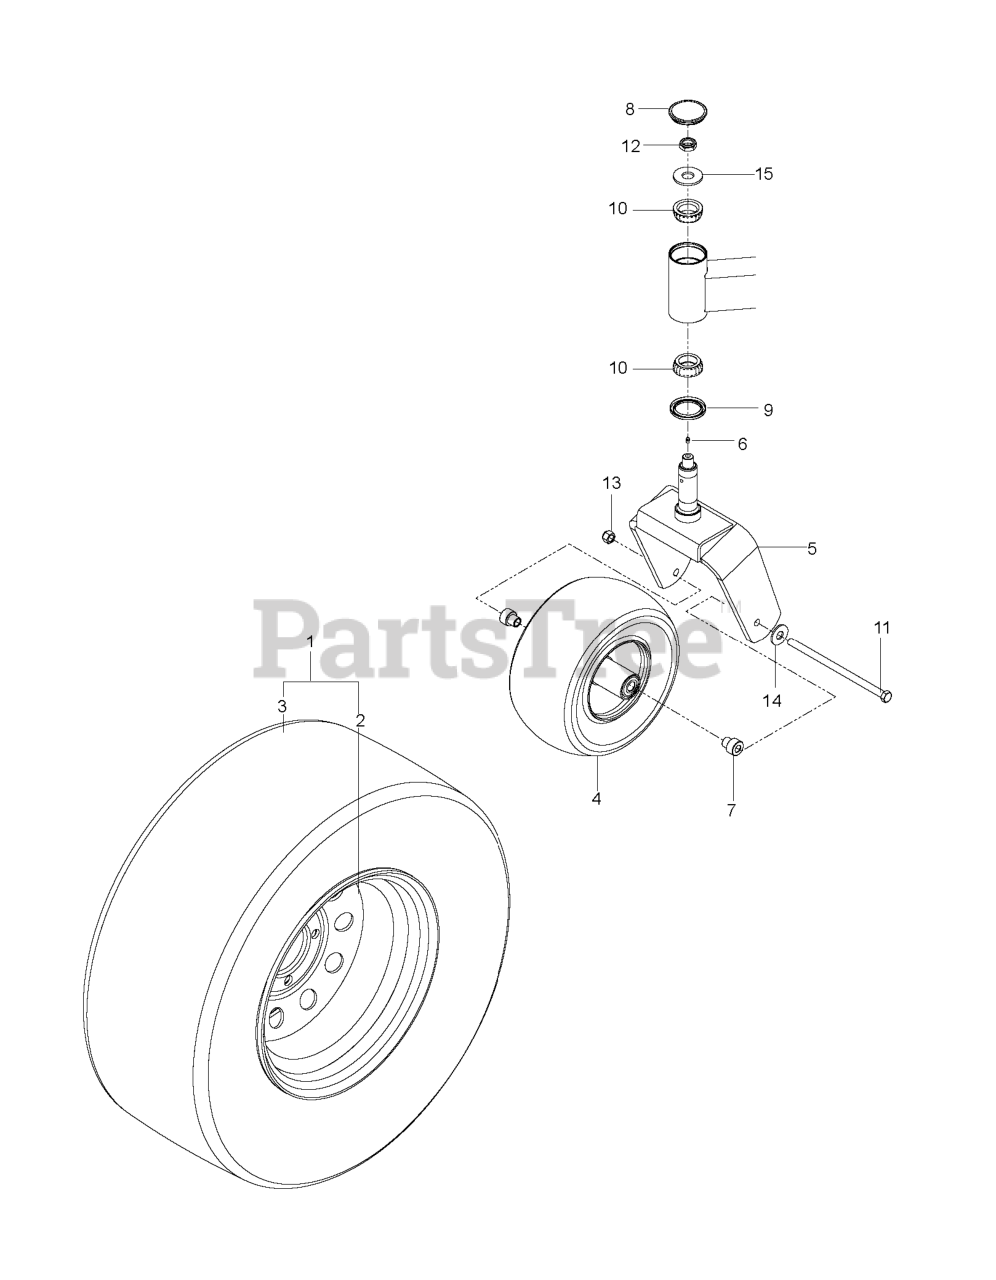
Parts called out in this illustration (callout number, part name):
1	WHEEL/TIRE.ASM.24X12-12.SILVER
2	12"RIM 2.5" NEG OFFSET 8.5" W
3	TIRE.24X12-12.TURF.MASTER
4	TIRE, 13 X 6.5-6 NO FLAT
5	FORK.CASTER.ORANGE
7	AXLE SPACER
9	SEAL, BEARING
10	BEARING W/CUP TAPPER ROLLER
11	HEX SCREW 1/2-13 X 9.5 GR5
12	NUT, 3/4-16 HEX THIN NYLOC ZD
13	NUT, 1/2-13 HEX FLG NYLOC ZD
14	WASHER 1/2" FLAT
15	WASHER, 3/4 HARDENED
